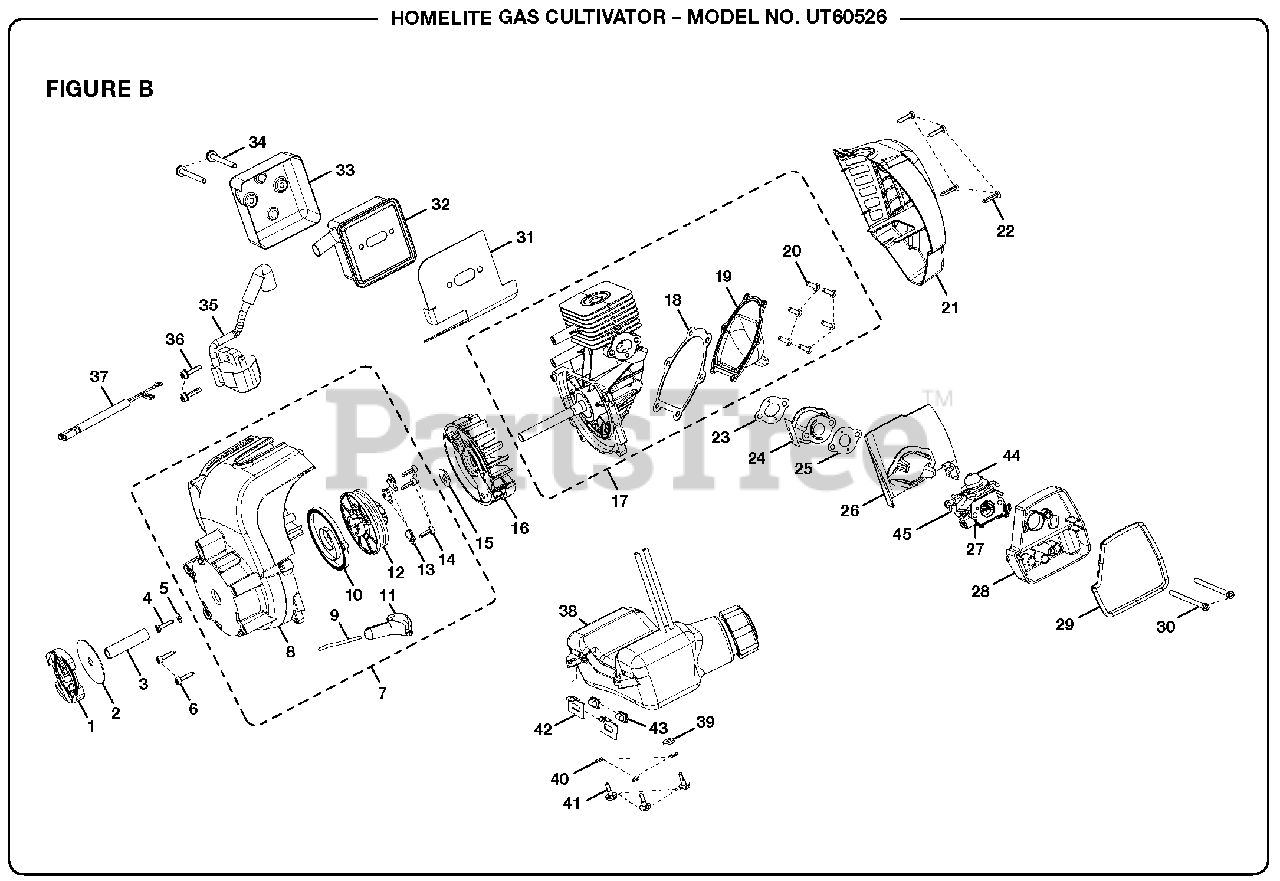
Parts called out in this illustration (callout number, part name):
1	Clutch Assembly
3	Spacer Tube
4	Screw (M4 x 20 mm)
6	Screw (M4 x 16 mm)
7	Lower Housing w/Starter Assembly Inc. Key Nos. 8-14)
8	Lower Housing Assembly
9	Starter Rope
10	Spring & Container Assembly
11	Grip
12	Starter Pulley
13	Pulley Retainer
14	Screw (M4 x 14 mm)
15	Washer
16	Flywheel Assembly
17	Short Block Assembly
18	Crankcase Cover Gasket
19	Crankcase Cover
20	Screw (M4 x 12 mm)
21	Top Housing
22	Screw (M4 x 18 mm)
23	Intake Gasket
25	Carburetor Gasket
26	Baffle Plate
27	Carburetor
28	Air Box Base
29	Air Box Seal
30	Muffler Bolt
31	Muffler Gasket
32	Muffler Assembly
33	Heat Shield
34	Screw (10-24 x 2-1/8 in.)
35	Ignition Module
36	Screw (M4 x 19 mm)
37	Lead Wire Assembly
38	Fuel Tank with Cap Assembly
39	Flat Washer
40	Spring Washer
41	Screw (M4 x 19 mm, Shoulder)
43	Bumper
44	Primer Bulb
45	Choke Lever
